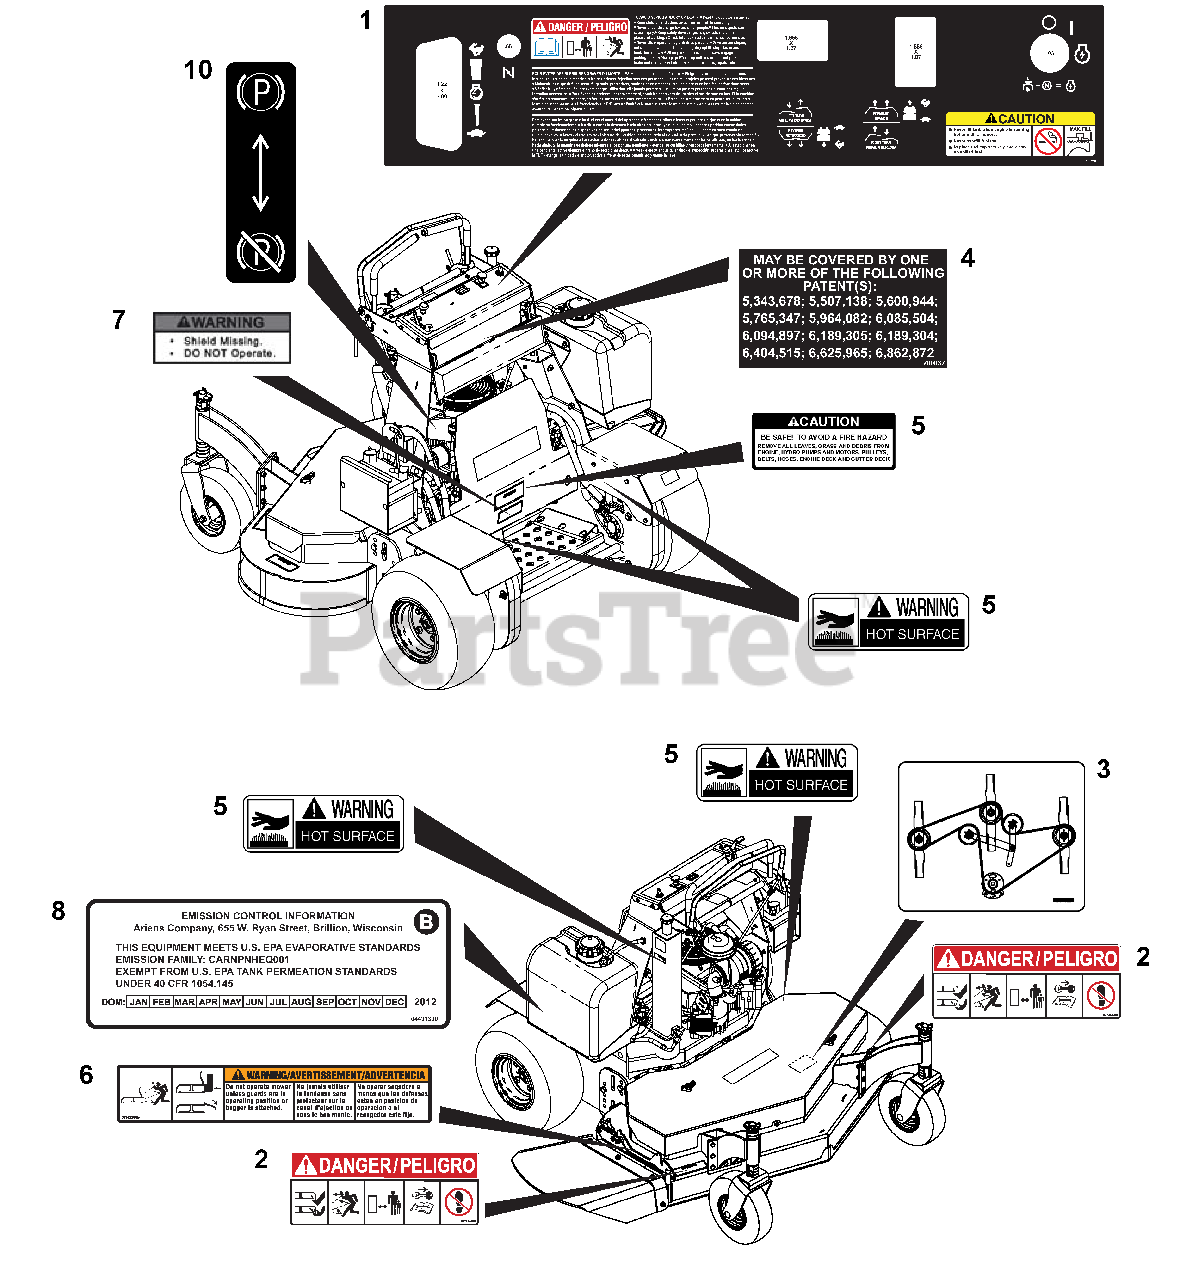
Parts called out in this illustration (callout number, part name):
1	DECAL, CONSOLE GRAVELY PROSTAN
2	DECAL, MOWER PAN DANGER
3	DECAL, BELT PATH
4	DECAL, PATENT
5	LABEL, WARNING (HOT SURFACES)
6	DECAL, WARNING
7	DECAL, WARNING - SHIELD
8	LABEL-EPA NON-COMP FUEL TANK12
9	DECAL, DEBRIS
10	LABEL - PARK BRAKE DIRECTION
